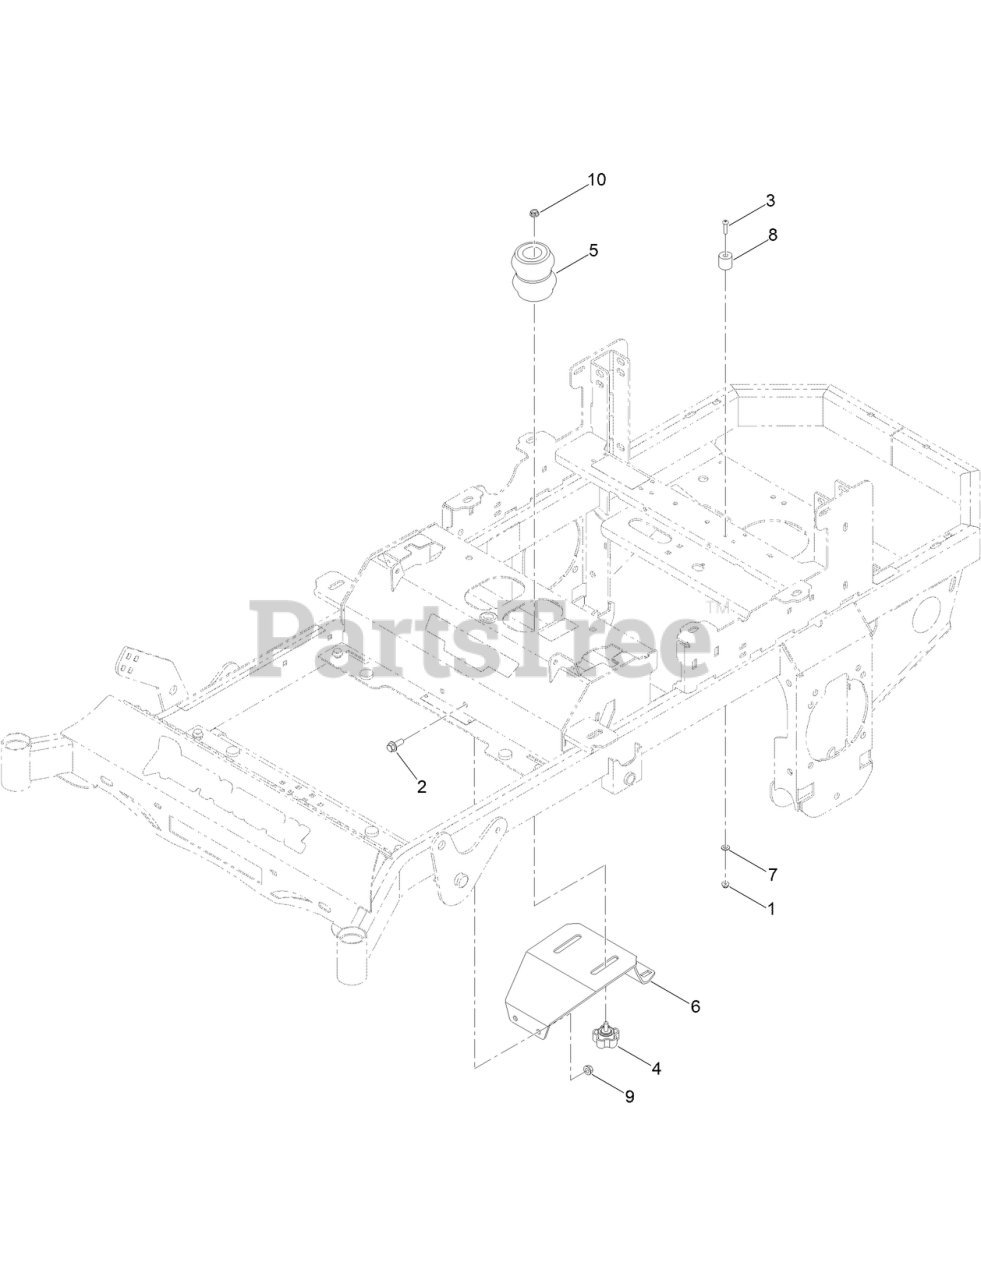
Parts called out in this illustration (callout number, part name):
1	NUT-HF
2	SCREW-HHF
3	1/4-20 X 1 BUTTON SOCKET C/S 18-8 SS
4	5/16-18X3/4 SL 5-LOBE MALE KNOB 1.90 DIA
5	SRT RR SUSP AND SEAT FT ELASTOMER TCB-3
6	MWR SEAT SUSP BRKT BLACK
7	WASHER-FLAT
8	HOOD REST RUBBER BUMPER
9	3/8-16 HEX FLANGE NUT W/SERR ZINC YELLOW
